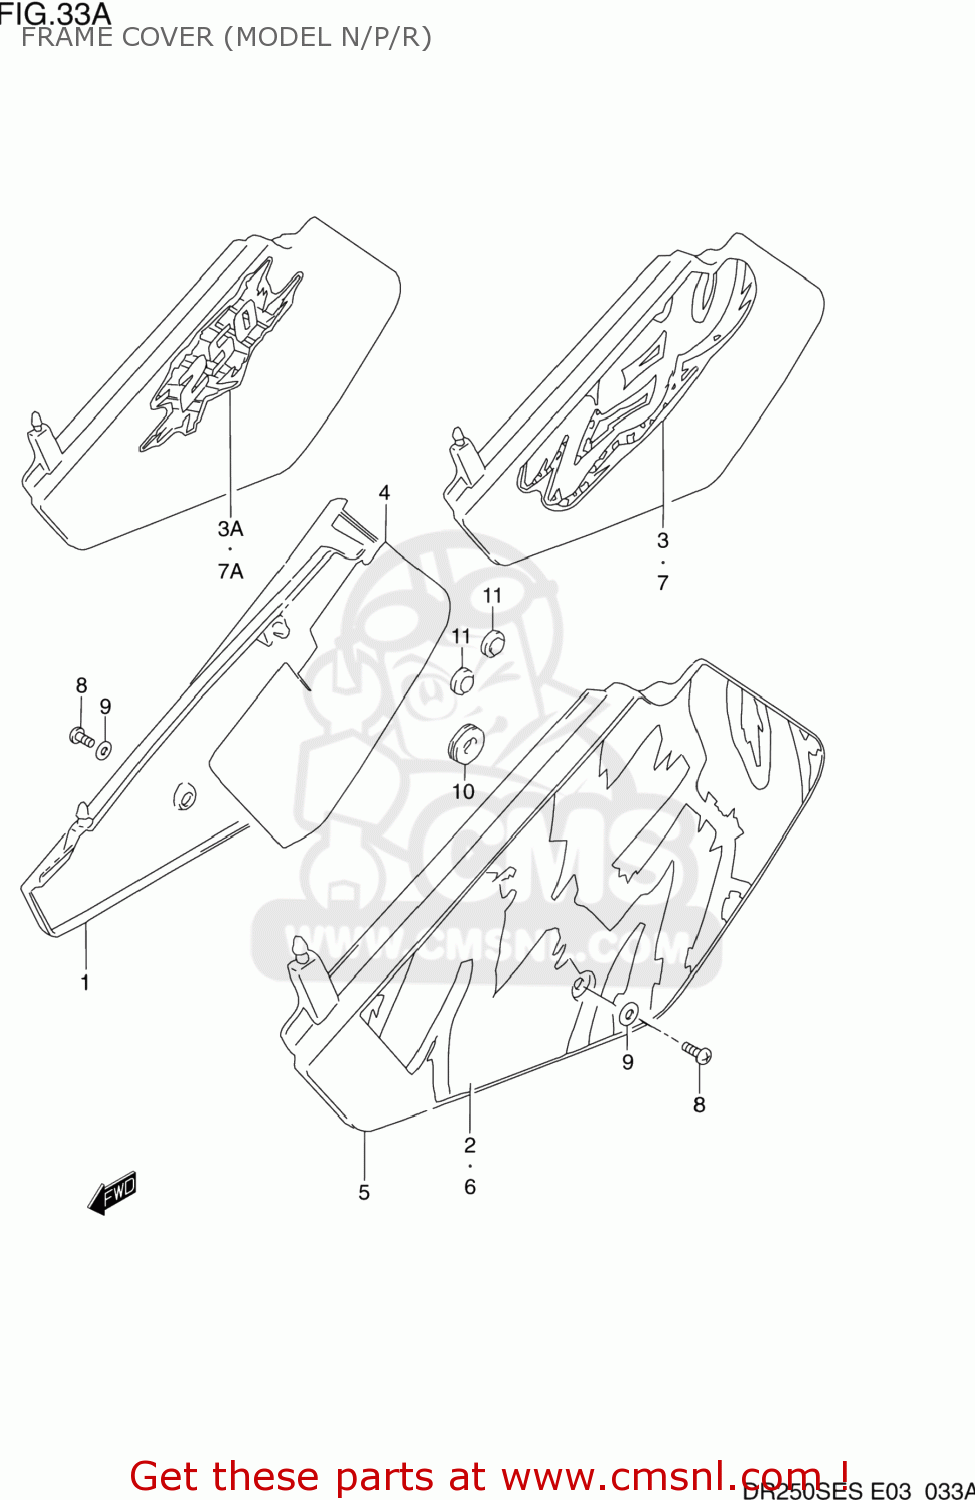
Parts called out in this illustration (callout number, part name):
1	COVER,FRAME,R(WHITE)
2	TAPE,FRAME COVER,RIGHT
3	EMBLEM,FRAME COVER,RIGHT
3A	EMBLEM,FRAME COVER
4	SHIELD,FRAME COVER,R
5	COVER,FRAME,L(WHITE)
6	TAPE,FRAME COVER,LEFT
7	EMBLEM,FRAME COVER,LEFT
7A	EMBLEM,FRAME COVER
8	SCREW
9	WASHER
10	CUSHION
11	CUSHION
